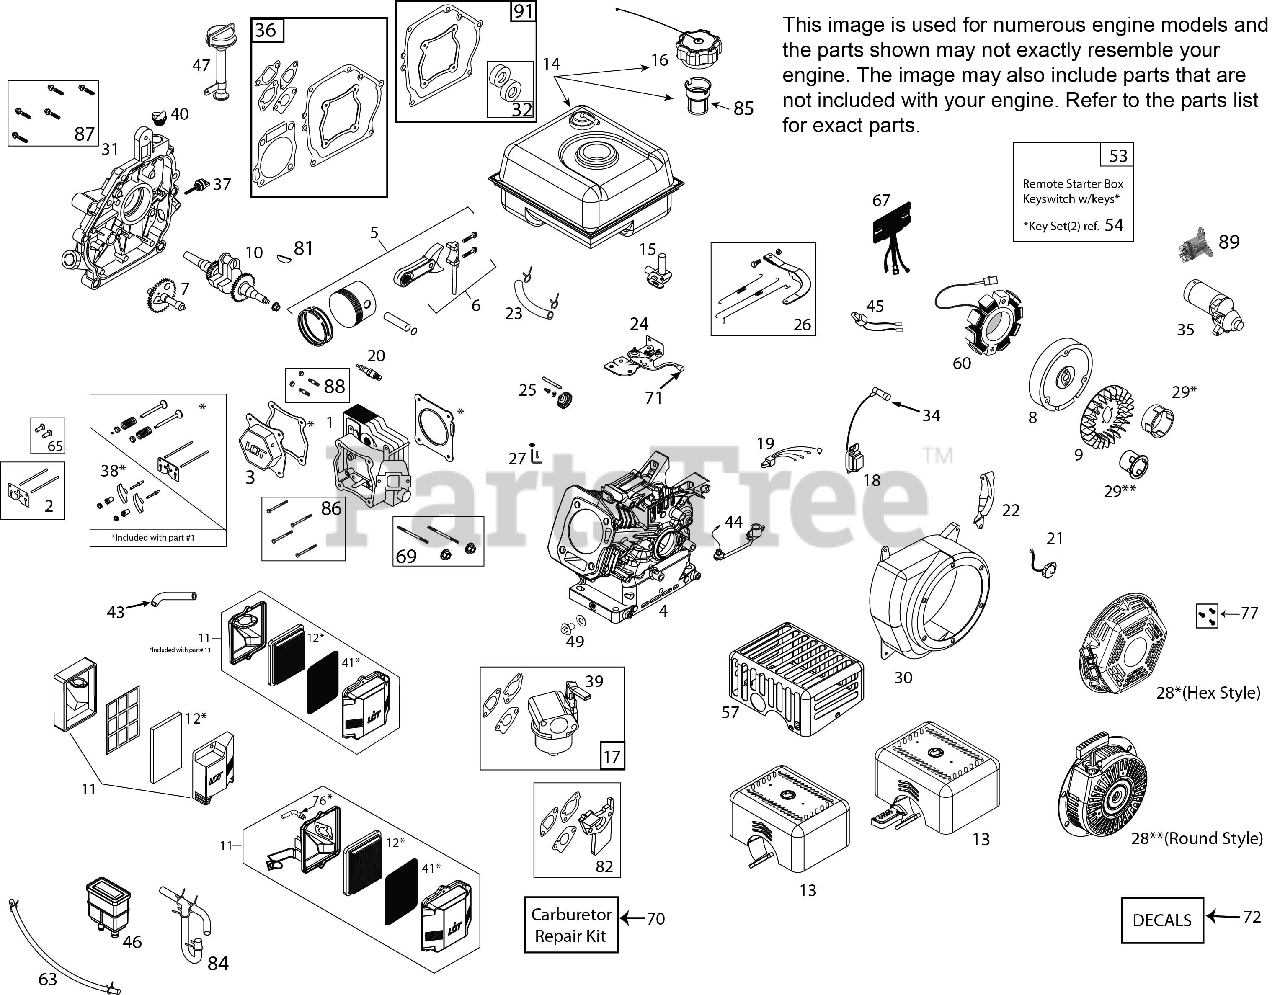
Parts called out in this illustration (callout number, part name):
1	CYLINDER HEAD ASSY(W/GASKET)
2	PUSH ROD & PLATE KIT(W/GASKET)
3	VALVE COVER (W/GASKET)
5	PISTON & ROD ASSEMBLY
7	CAMSHAFT - MCR(W/COVER GASKET)
8	FLYWHEEL - MANUAL START
9	COOLLNG FAN - FLYWHEEL (PLSTC)
10	CRANKSHAFT (#14 KEYED)
11	AIR FILTER ASSY - COMPLETE
12	AIR FILTER ELMNT (W/PRE-FLTER)
13	MUFFLER ASSY (W/CATALYST)
14	FUEL TANK BLACK W/PLASTIC CAP
15	FUEL TANK ON/OFF VALVE (1/4")
16	FUEL TANK CAP
17	CARBURETOR (W/GSKTS & SPACER)
18	IGNITION COIL (EPA III)
20	SPARK PLUG, ARIENS AX
21	ENGINE STOP SWITCH (TWO WIRE)
22	SHIELD - FLYWHEEL - MNL START
23	FUEL HOSE KIT 1/4-318MM
24	SPEED CONTROL (MANUAL)
25	GOVERNOR GEAR ASSEMBLY
26	GOVERNOR ARM & LINK KIT
27	GOVERNOR ARM PADDLE
28	RECOIL STARTER (ROUND - BLACK)
29	STARTER CUP
30	BLOWER HOUSING (W/SWITCH HOLE)
31	CRANKCASE COVER ASSY
32	OIL SEAL KIT
34	SPARK PLUG
36	ENGINE GASKET KIT
37	SMALL BLACK OIL DIPSTICK
38	ROCKER ARM KIT (W/GASKET)
39	CHOKE LVR & SCREW 136CC SUMMER
40	NON-REMOVABLE PLASTIC PLUG
41	POLY PRE-FILTER P AIR CLEANER
43	BREATHER TUBE
49	OIL DRAIN PLUG (W/WASHER)
65	TAPPET KIT (SET OF 2)
69	CARB MTG STD KIT 136CC SUMMER
70	CARBURETOR REPAIR KIT
77	RECOIL BOLT KIT
81	WOODRUFFF FLYWHEEL KEY 5-PACK
82	CARBURETOR SPACER
85	FUEL TANK STRAINER
86	HEAD BLT KIT 136-179-208-254CC
87	CRANKCASE COVER BOLT KIT 136CC
88	MUFFLER MTG STUD KIT
91	CRANKCASE GASKET KIT (136CC)
